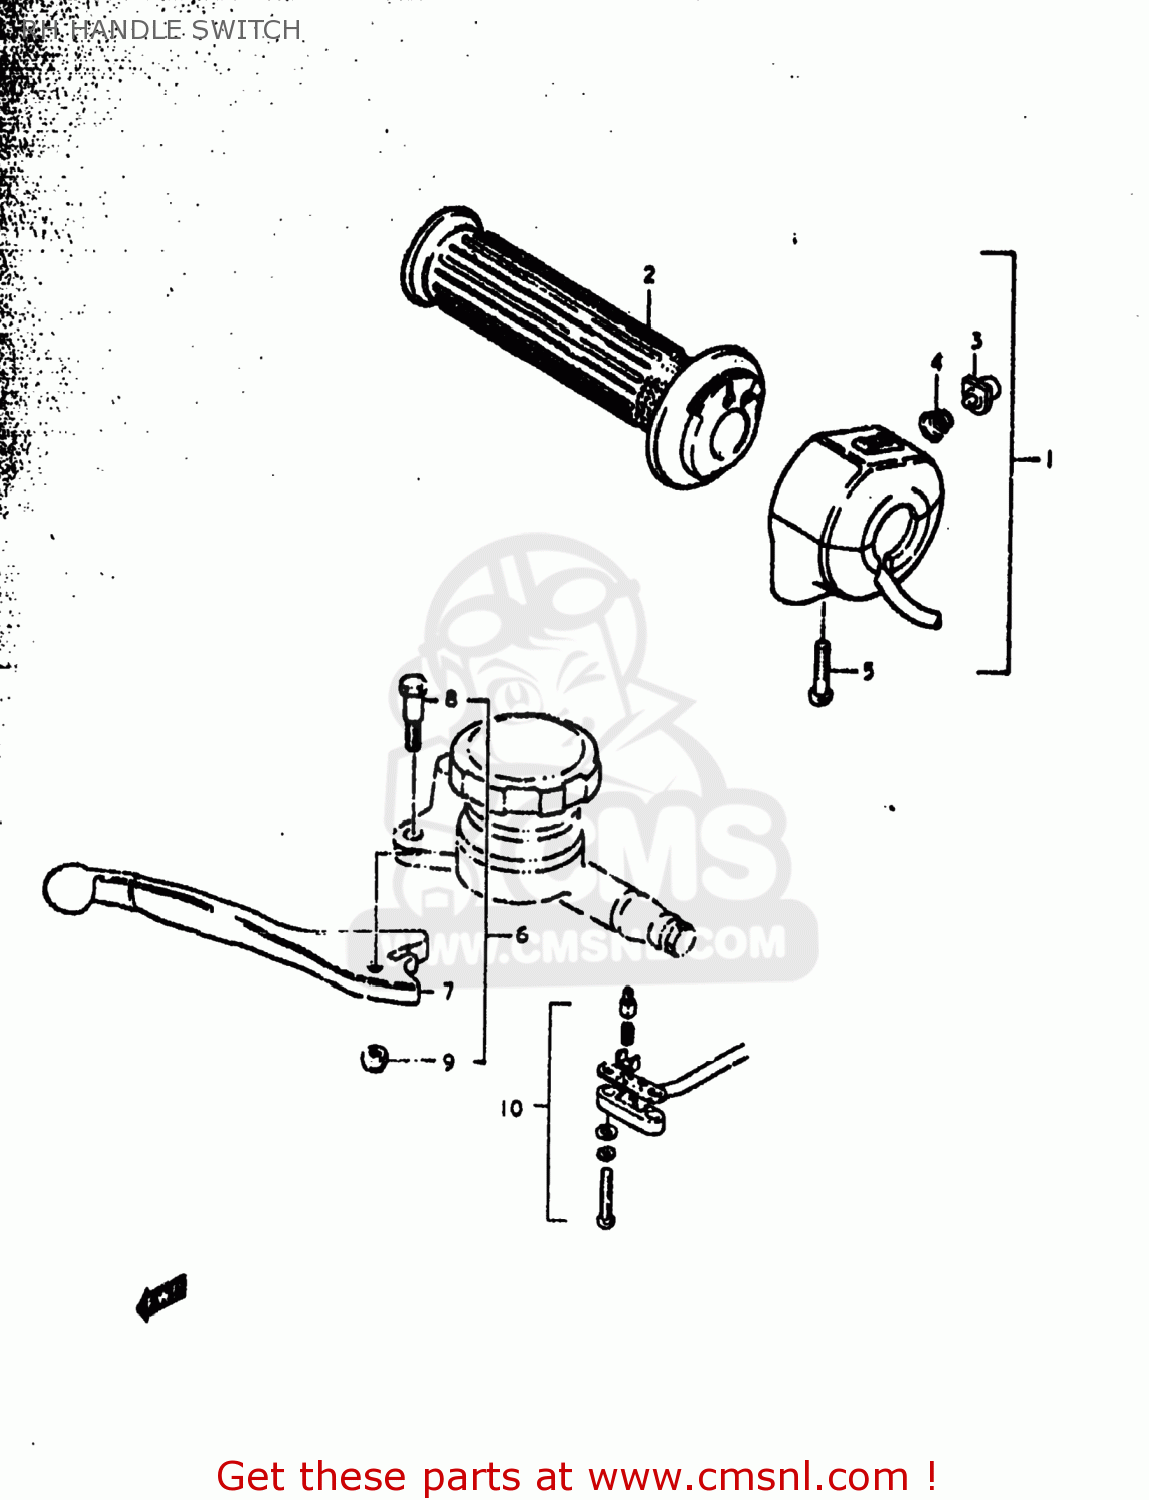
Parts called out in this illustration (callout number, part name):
1	CASE ASSEMBLY,THROTTLE
2	GRIP,THROTTLE
3	BUTTON
4	SPRING
5	SCREW
6	LEVER ASSEMBLY,BRAKE
7	LEVER,BRAKE
8	BOLT,LEVER
9	NUT 6MM
10	SWITCH ASSY,STOP
